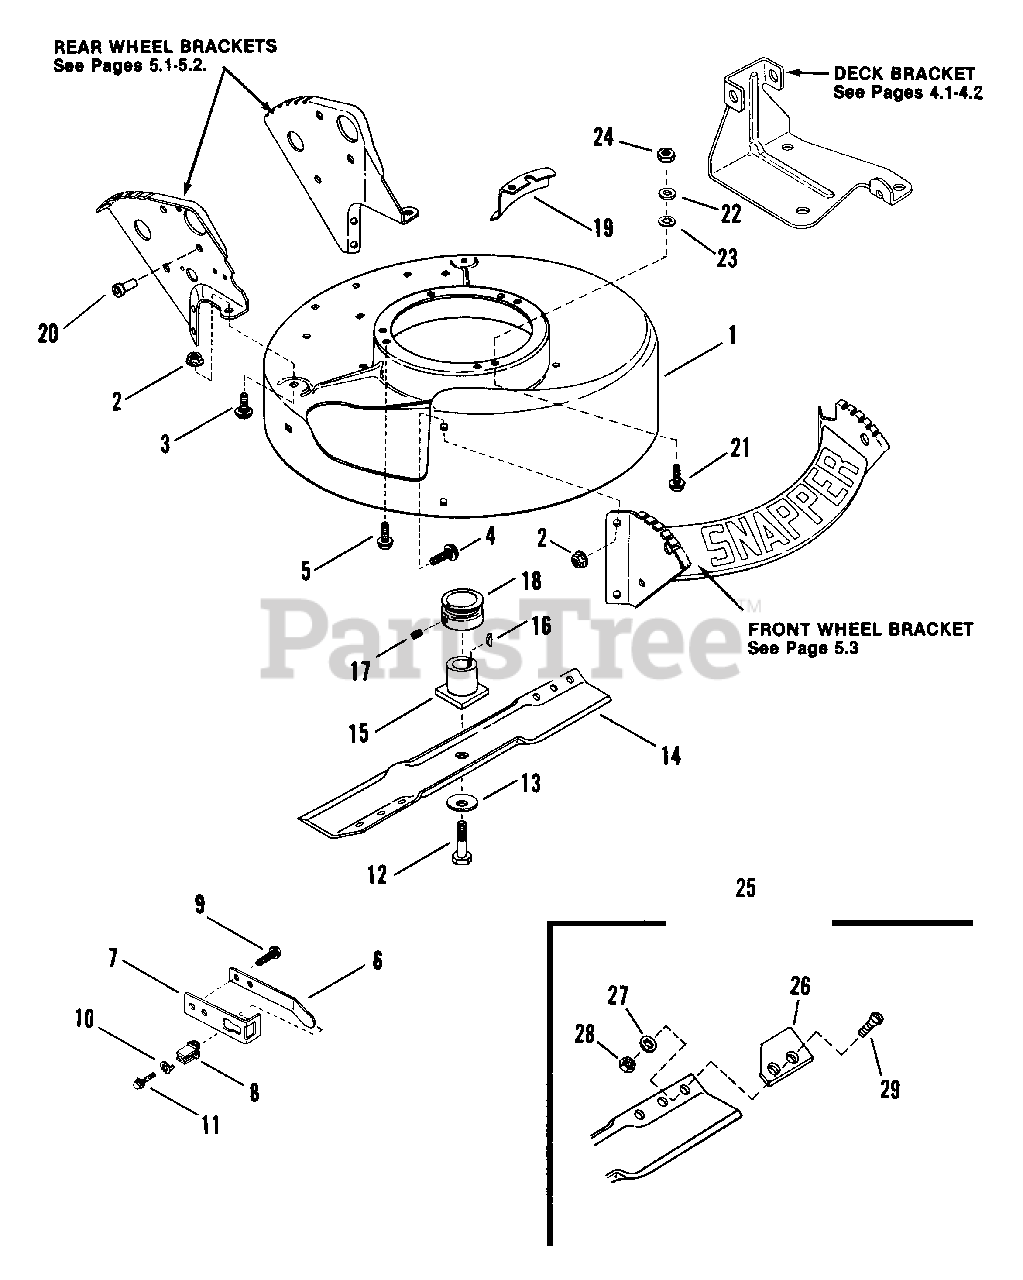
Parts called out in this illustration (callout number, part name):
1	DECK, Mower (Painted deck/decals)
2	NUT, 5/16-18 Hex Flange Lock
3	BOLT, 5/16-18x1/2" Short Neck Carriage (Gr.)
4	BOLT, 5/16-18x1" Short Neck Carriage
5	SCREW, 3/8-16x1" Self-tapping (Engine Mounting)
6	SPRING, Wheel Bracket Type Interlock
7	BRACKET, Wheel Bracket Type Interlock
8	INSULATOR, Interlock
9	SCREW, 1/4-20x1/2" Self-tapping
10	WASHER, #8Tab Internal Tooth Lock
11	SCREW, #8-18x3/4" Hex Head Machine
12	SCREW, 3/8-24x2" Hex Head Cap (Gr. 5)
13	WASHER, Cone
14	BLADE, Cutter(For 3-1/2 HP only)
14	BLADE, Cutter, (4 HP ENGINES)(Replaces 1-9710 & 1-9702)
15	HUB, Blade Drive (7/8" Dia. I.D.)
15	HUB, Blade Drive (25mm Dia. I.D.)
16	KEY, Hi-Pro
17	SCREW, 5/16-18x5/16" Hex Socket Set
18	PULLEY, Engine (7/8" I.D. x 1-718" O.D.)
18	PULLEY, Engine (7/8" I.D. x 2-1/8" O.D.)
18	PULLEY, Engine (25mm I.D. x 2-1/8" O.D.)
19	SHIELD, Belt Opening Cover
20	BUSHING, Interlock Wire
21	BOLT, 5/16-18x1 1/2" Hex Flange Lock
22	WASHER, 5/16 Flat
23	WASHER, 5/16 Split Lock
24	NUT, 5/16-18 Hex
25	KIT, Air Lift, 21"
26	LIFT, Air, 21" Blade
27	LOCKWASHER
28	NUT, 5/16-24 Hex
29	SCREW, 5/16-24 Machine
